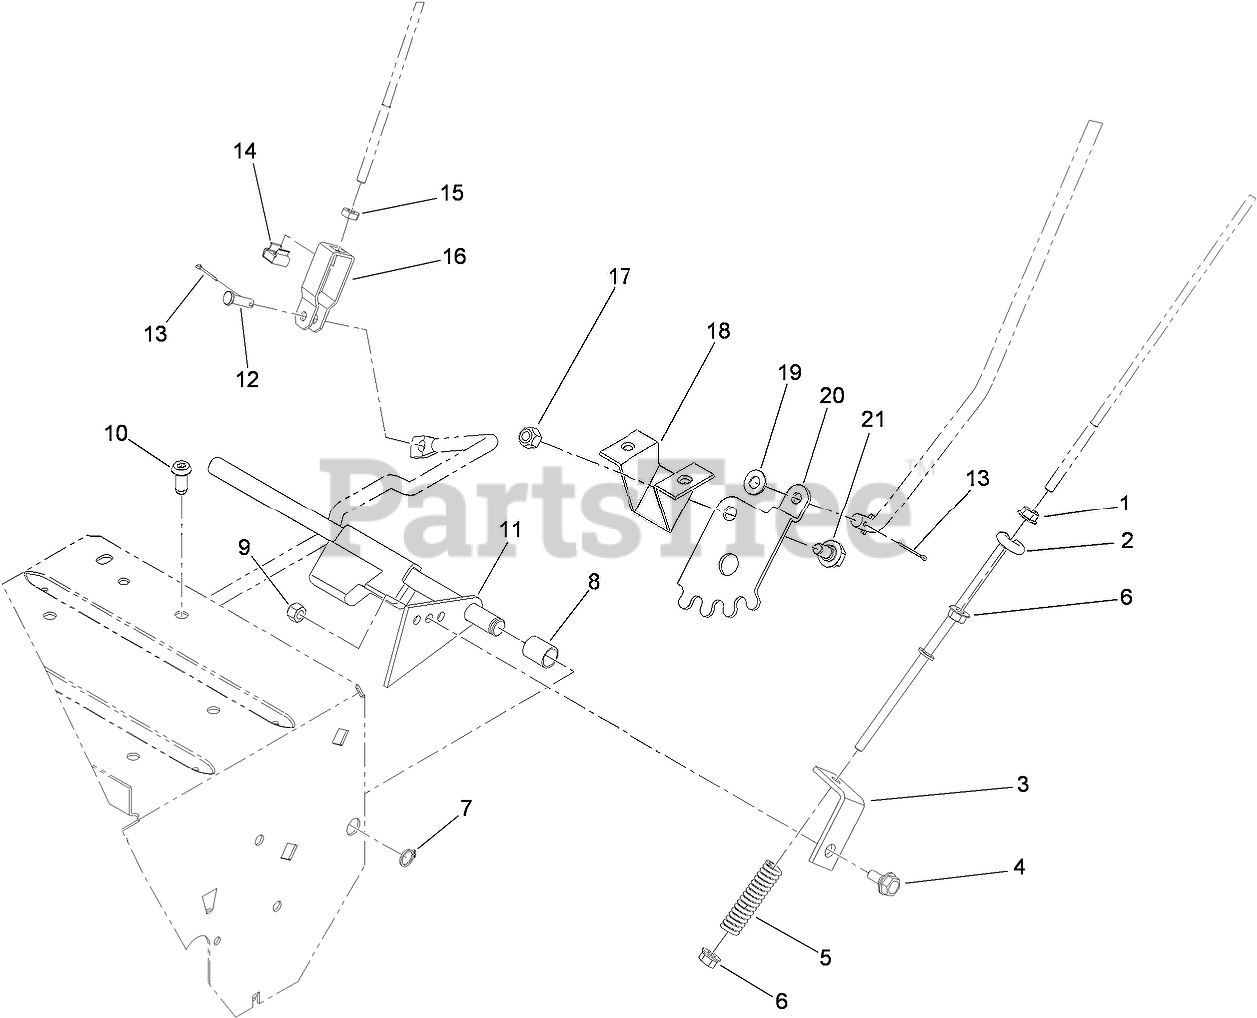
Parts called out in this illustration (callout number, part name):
1	NUT-HF
2	ROD-TRACTION, LOWER
3	BRACKET-TRACTION
4	SCREW
5	SPRING
6	NUT-HHF
7	RING-RETAINING
8	SPACER
9	NUT-LOCK, NI
10	SCREW-BUTTON HEAD
11	TRACTION ARM ASM
12	PIN-CLEVIS
13	PIN-COTTER
14	NUT-RETAINED
15	NUT-JAM
16	CLEVIS
17	NUT-LOCK, NI
18	MOUNT-LEVER
19	WASHER-PLAIN
20	GEAR-QUADRANT
21	BOLT-SHOULDER
